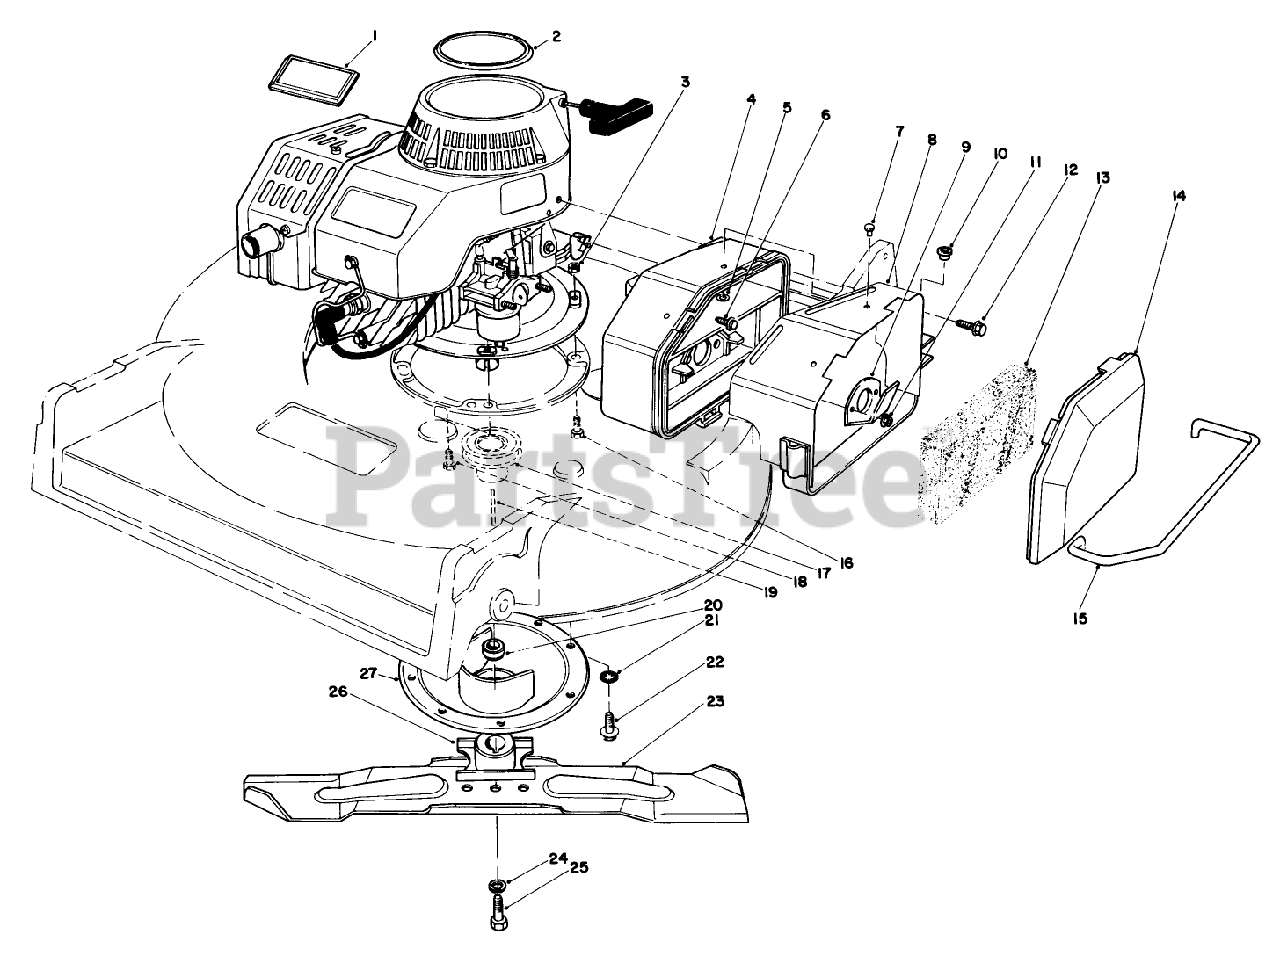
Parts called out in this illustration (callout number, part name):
1	Plate-Logo
2	Plate-Engine Logo
3	NUT-JAM
4	AIR CLEANER ASM
5	WASHER-FLAT
6	HEX FL HD M.6X1.0X25MM
7	RIVET-POP
8	AIR CLEANER COVER WA
9	SPIT BACK DEFLECTOR
10	5/16 ID BSHG
11	NUT-LOCK
12	SCREW-HHF
13	FILTER
14	AIR CLEANER COVER
15	AIR CLEANER GUARD
16	SCREW-HH
17	PULLEY-DRIVER
18	SCREW-HH
19	KEY-SQUARE
20	SPACER-BLADE RETAINER
21	WASHER-LOCK, INTERNAL
22	SCREW-HWHTF
23	BLADE-21in
24	WASHER-LOCK
25	SCREW-BLADE
26	RETAINER-BLADE
27	Crankshaft Protector Assy.
